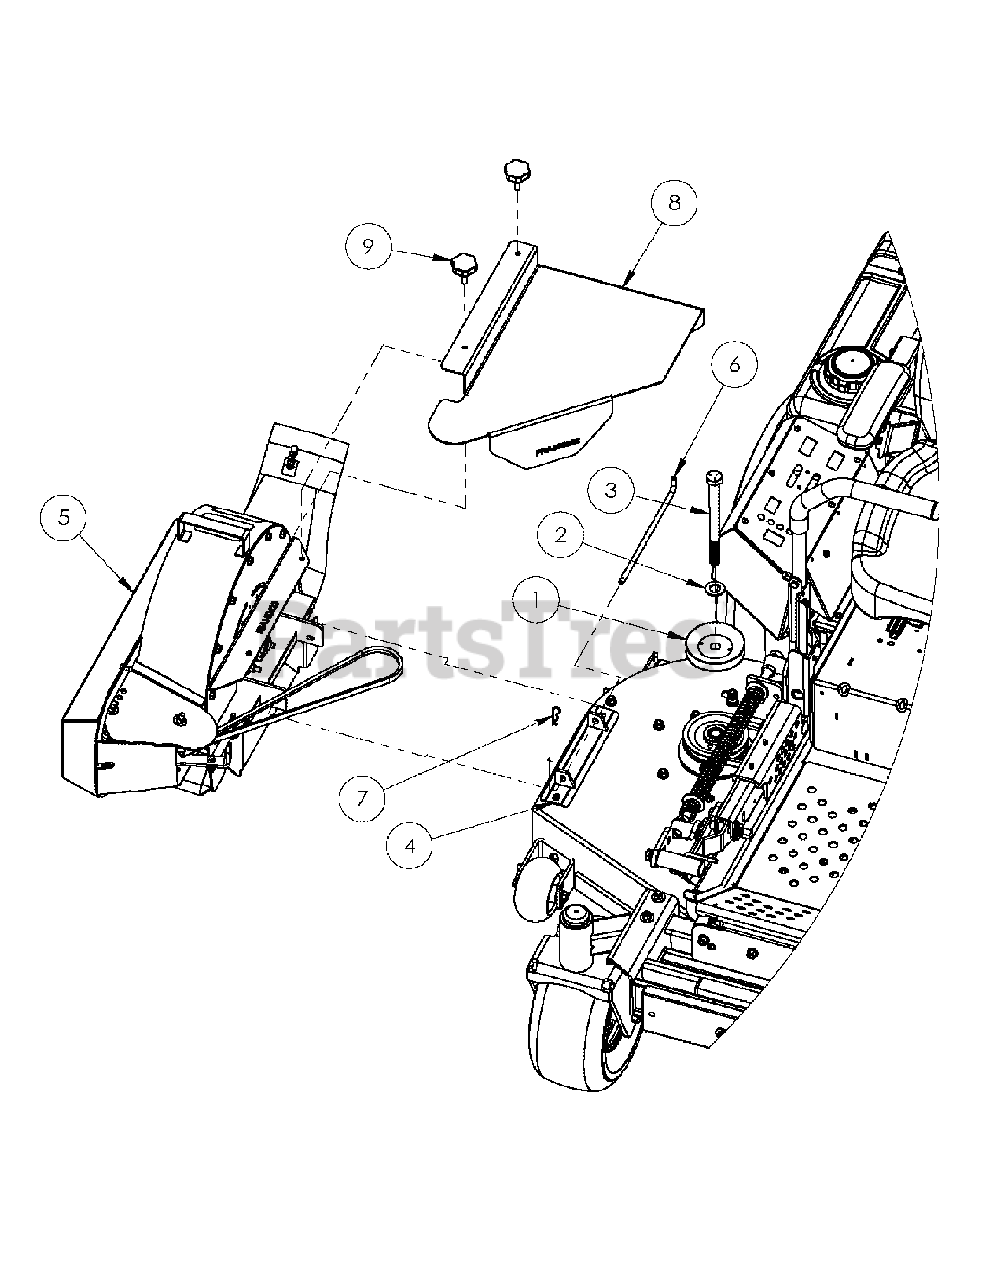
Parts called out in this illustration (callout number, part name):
2	WASHER
3	CAP SCREW 3/4-16 X 8 3/4" LONG
4	DECK MOUNTING BRACKET
5	VERTICAL BLOWER ASSEMBLY
6	MOUNTING PIN
8	BELT COVER DECK
9	RELEASE KNOB
